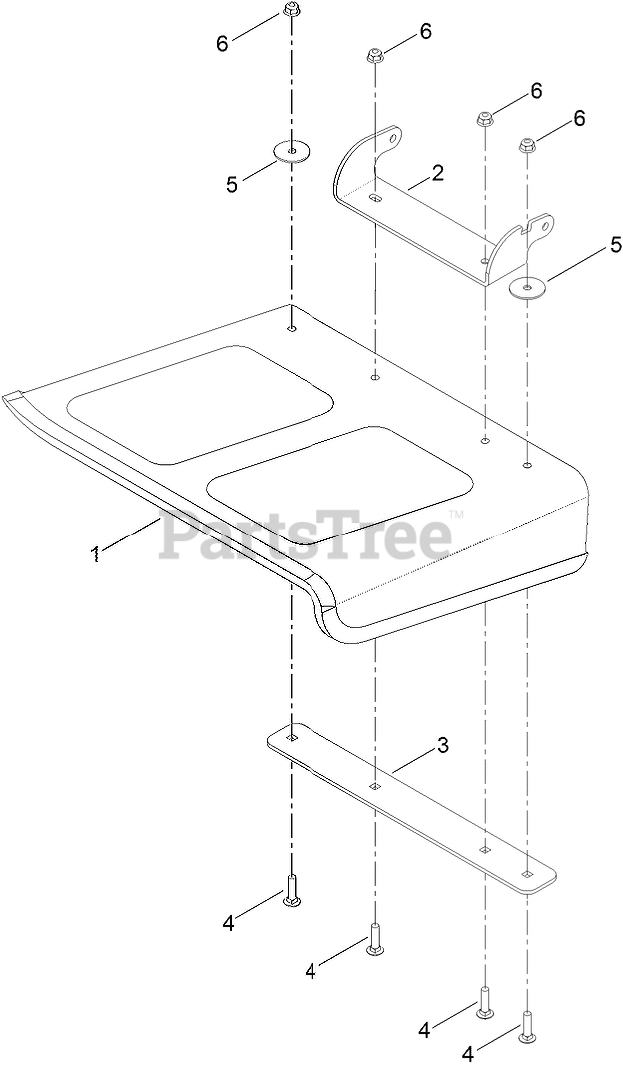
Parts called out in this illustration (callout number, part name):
1	DEFLECTOR
2	BRACKET-DEFLECTOR, UPPER
3	PLATE-DEFLECTOR
4	SCREW-CARR
5	WASHER-FLAT
6	NUT-HF, NI
